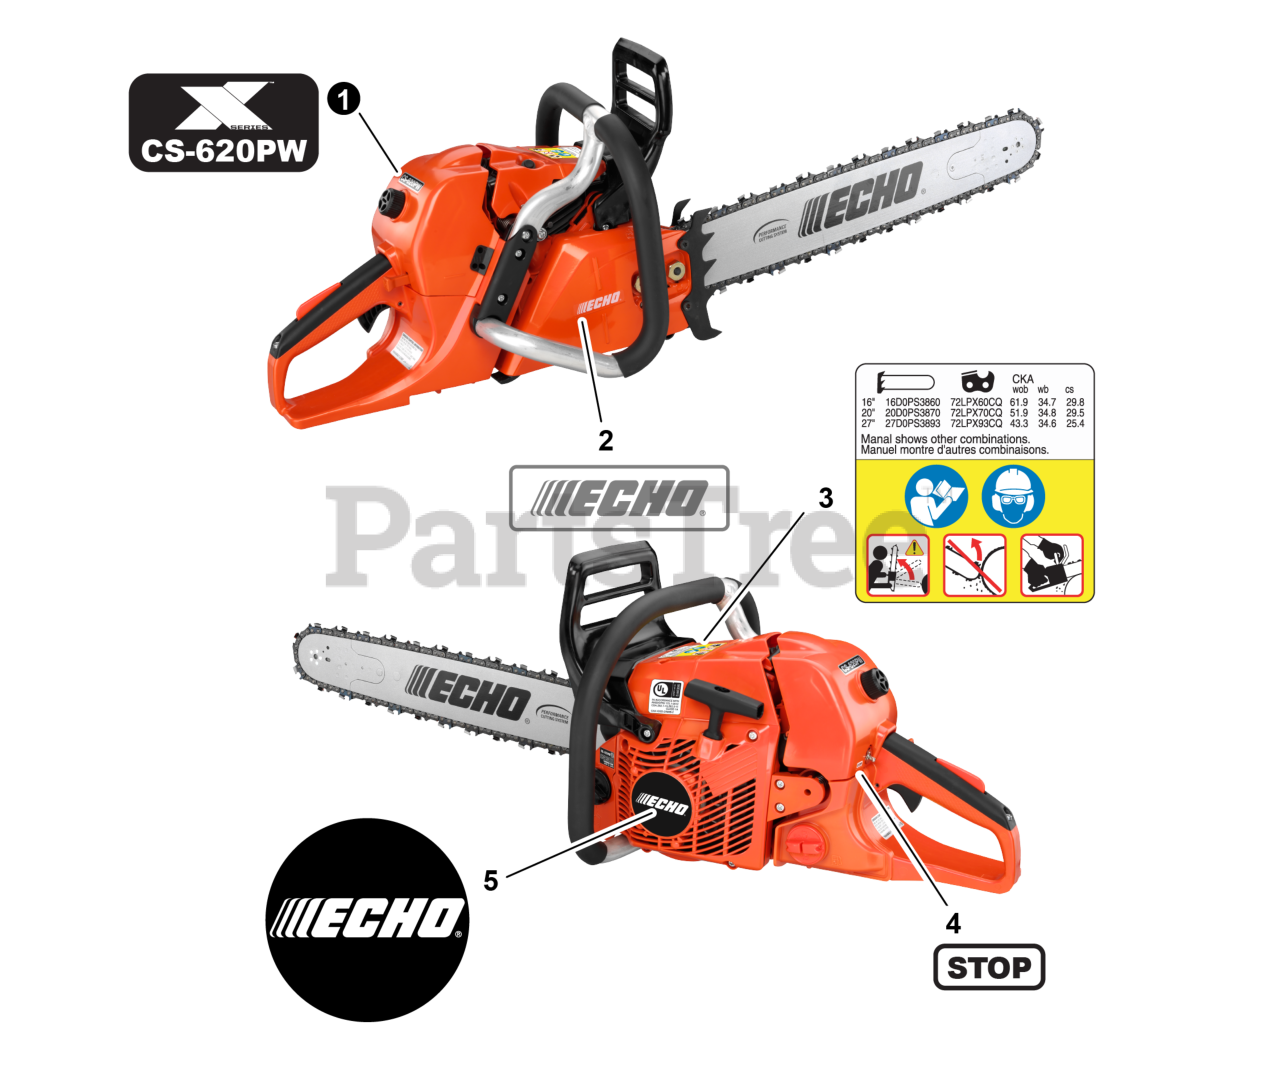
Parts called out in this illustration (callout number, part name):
1	LABEL - MODEL CS-620PW
2	LABEL - ECHO
3	LABEL - CAUTION
4	LABEL - STOP
5	LABEL - RECOIL STARTER
